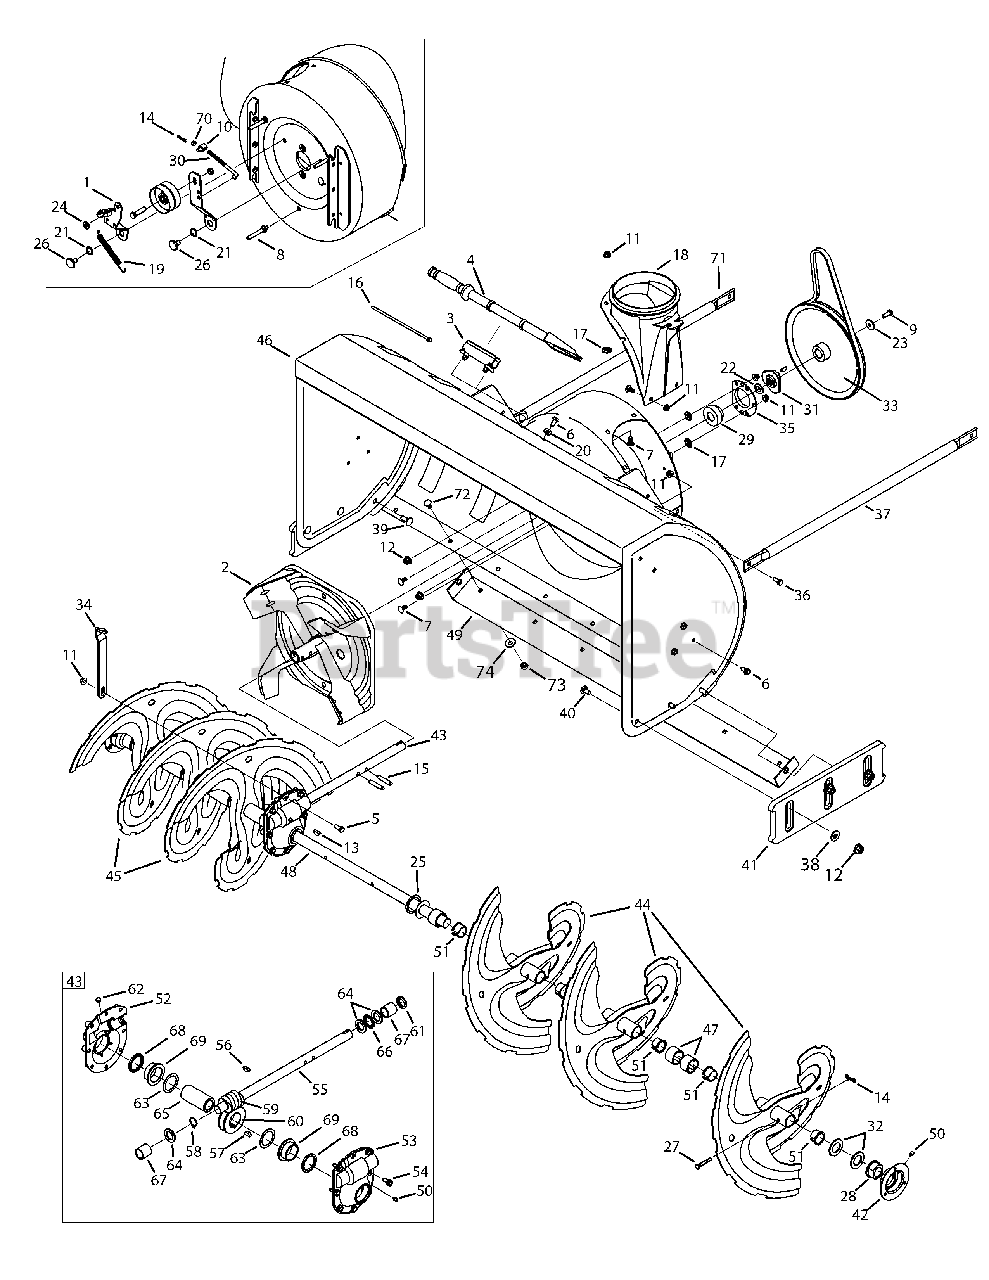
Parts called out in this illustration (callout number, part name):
1	Bracket Assembly, Auger Brake
2	Impeller , 16"
3	Clip, Mounting
4	Tool, Clean-out
5	Screw, Hex Cap, 5/16-18 x 1.0 Gr5
6	Screw, 5/16-18 x .750
7	Screw, Carriage, 5/16-18 x .75
8	Screw w/Stud, 5/16-18 x .4300
9	Screw, Hex Cap Lock, 5/16-24, 875
11	Nut, Hex Flange Lock, 5/16-18
12	Nut, Hex Flange Lock, 3/8-16
13	Key, Woodruff, 1/4 x 3/4
14	Pin, Bow-tie Cotter
15	Pin, Spiral, 5/16 x 1.75
16	Cable Tie
17	Nut, Push
18	Adapter, Chute, 6"
19	Spring, Extension
20	Washer, Flat, .349 x .879 .063
21	Washer, Wave, .625 x .885 x .015
22	Washer, Bell., .78 x 1.49 x .06
23	Washer, Flat, .34 x 1.5 x .15 Ht.
24	Washer, .344 x .75 x .12
25	Washer, 1.01 x 1.86 x .06
26	Screw, Shoulder, .625 x .17
27	Pin, Shear, .25 x 1.75
28	Bearing, Flange w/Flats
29	Bearing, Self Aligning
30	Rod, Auger Idler
31	Adapter, Pulley w/Pins
32	Spacer, 1.004 x 1.375 x .25
33	Pulley, Auger Drive, 10.0
34	Bracket, Gear Box Support
35	Housing, Bearing
36	Screw, 5/16-18 x .75 GR5
37	Tube, Support , LH
38	Washer, Flat, .385 x .870 x .092
39	Screw, Carriage, 3/8-16 x .75
40	Screw, Carriage, 3/8-16 x 1.00
41	Shoe Skid, Deluxe - Blue
42	Housing, Bearing
43	Gear Box Assembly
44	Spiral Assembly, LH
45	Spiral Assembly, RH
46	Housing, Auger - 45"
47	Spacer, 1.50 x 1.00 x 1.00
48	Axle, Spiral
49	Shave Plate, 45"
50	Grease Fitting, 3/16
51	Flange Bushing
52	Housing Assembly, Auger, RH
53	Housing Assembly, Auger, LH
54	Screw, LD, 5/16-18 x .750
55	Auger Drive Shaft
56	Key, Hi Pro, 3/16 x 3/4
57	Key, 1/4 x 3/4 Dia.
58	External Retainer Ring
59	Gear, Worm
60	Gear, Worm, LH
61	Seal, Oil
63	Wash, Flat, 1.52ID x 2.0 OD
64	Wash, Flat, .88 ID x .38 OD
65	Worm Gear Shaft
66	Bearing, Thrust
69	Flange Bearing
70	Jam Nut, 5/16-18
71	Tube, Support, RH
72	Screw, Carriage, 5/16-18 x .750
73	Nut, Hex, 5/16-18
74	Washer, Bell., .34 x .872 x .060
